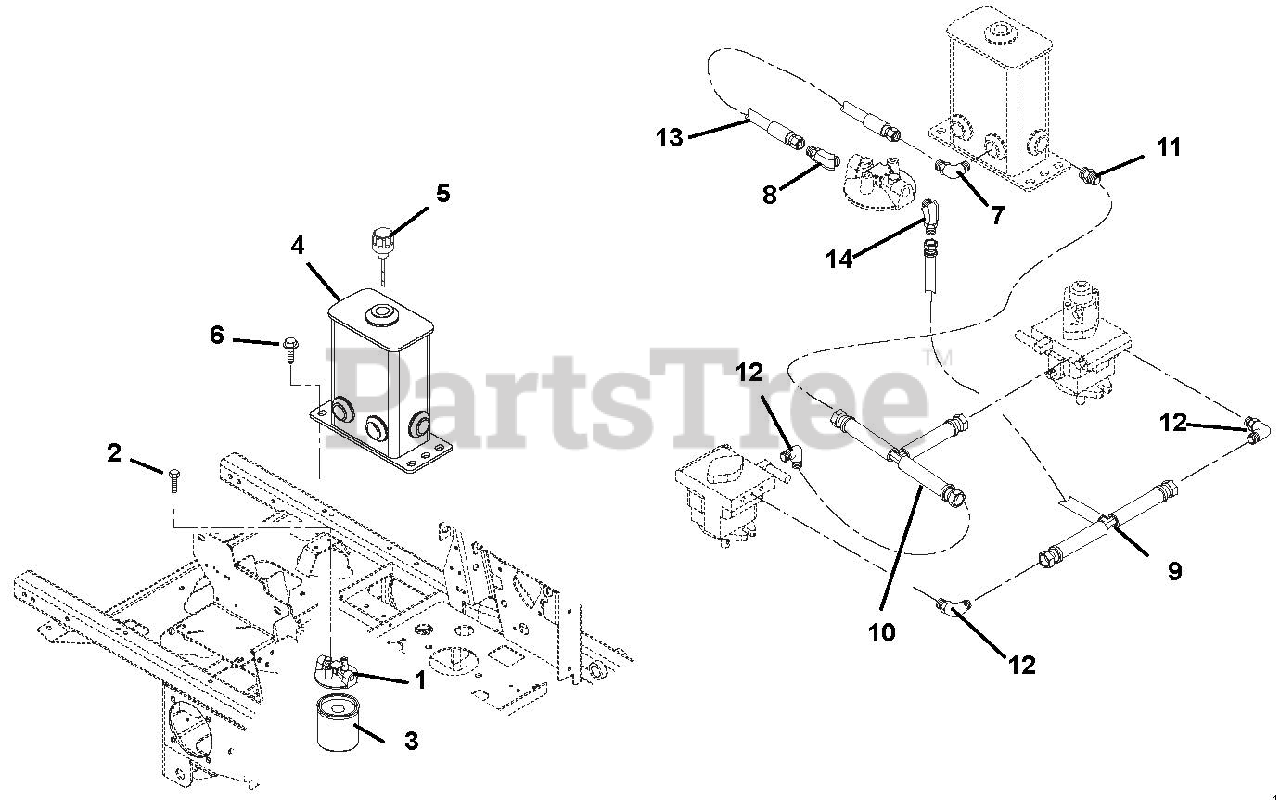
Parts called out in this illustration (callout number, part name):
1	Head, Filter
2	Bolt, Hex .25-20 x .50 Epoxy Grade 5
3	Oil Filter
4	Weldment, Formed Hydraulic Tank-2 PORT
5	Dipstick, Breather
6	Screw, Tapping .38-16 x .75 Hex Washer Head
7	Fitting, Hydraulic, 90 Degree Elbow, Steel M8F-M80
8	Fitting, Hydraulic Straight M80-M80
9	Hose, .50 To .38 Tee Assembly
10	Hose, .38 Tee Assembly
11	Fitting, Hydraulic Straight M10O-M8F
12	Fitting, Hydraulic
13	Hose, Hydraulic Molded
14	Fitting, Hydraulic 45° M80-M80
